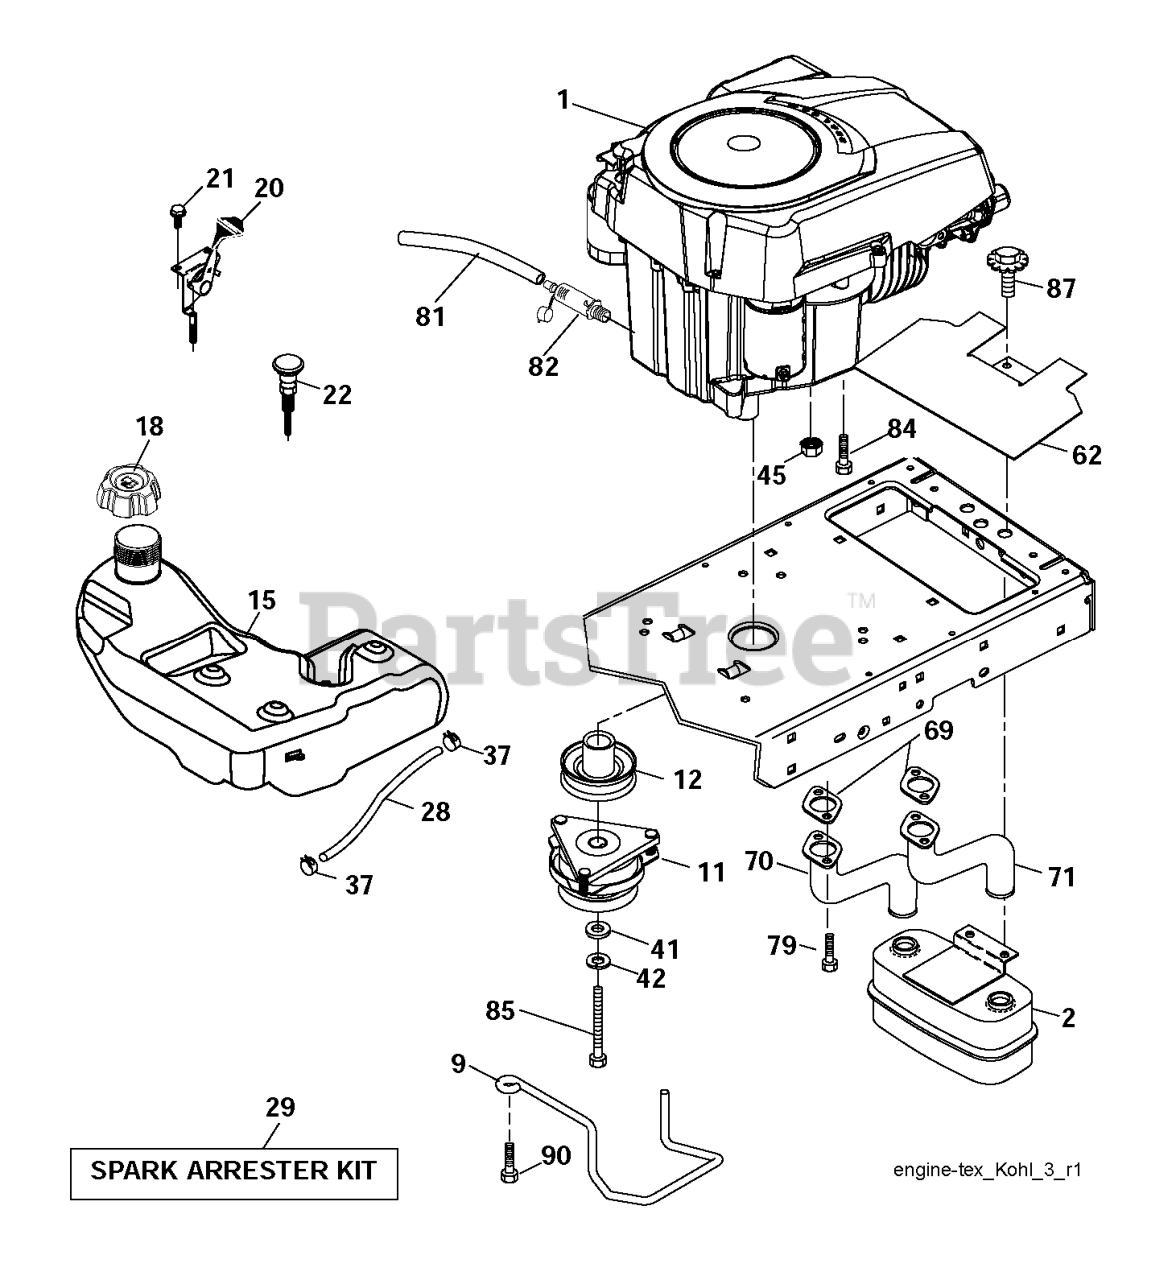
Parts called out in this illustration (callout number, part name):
2	MUFFLER.TWIN.CYL.LOW.TONE
9	KEEPER.BELT.ENGINE.4.2
11	CLUTCH MZ ZTR GT.48/54"1.125"
12	PULLEY ENGINE
15	TANK.FUEL.4GAL
18	CAP.FUEL.TANK.3"GREY
20	THROTTLE CONTROL
21	SCREW.#10 X 0.750.BOS
22	CONTROL.CHOKE.ERGO.PUSH-IN.BLA
28	REPL BY 532 00 85-43
29	KIT.SPARK ARRESTOR 794945 B&S
37	HOSE CLAMP
42	LOCKWASHER
45	NUT
62	RP SHIELD HEAT MUFFLER
69	GASKET.EXHAUST.KOHL.CV18-CV26
70	RP.PIPE-EXHAUST LH
71	RP.PIPE-EXHAUST RH
79	SCREW.SOCKET HD.5/16-1
81	TUBE, DRAIN OIL ASM.
82	PLUG DRAIN OIL EASY
84	SCREW 3/8-16X1
85	BOLT HEX 7/16-20 X 3.75 GR. 5
87	BOLT.5/16-18UNCX1.W/SEMS.BLK
90	SCREW 3/8-16X1
